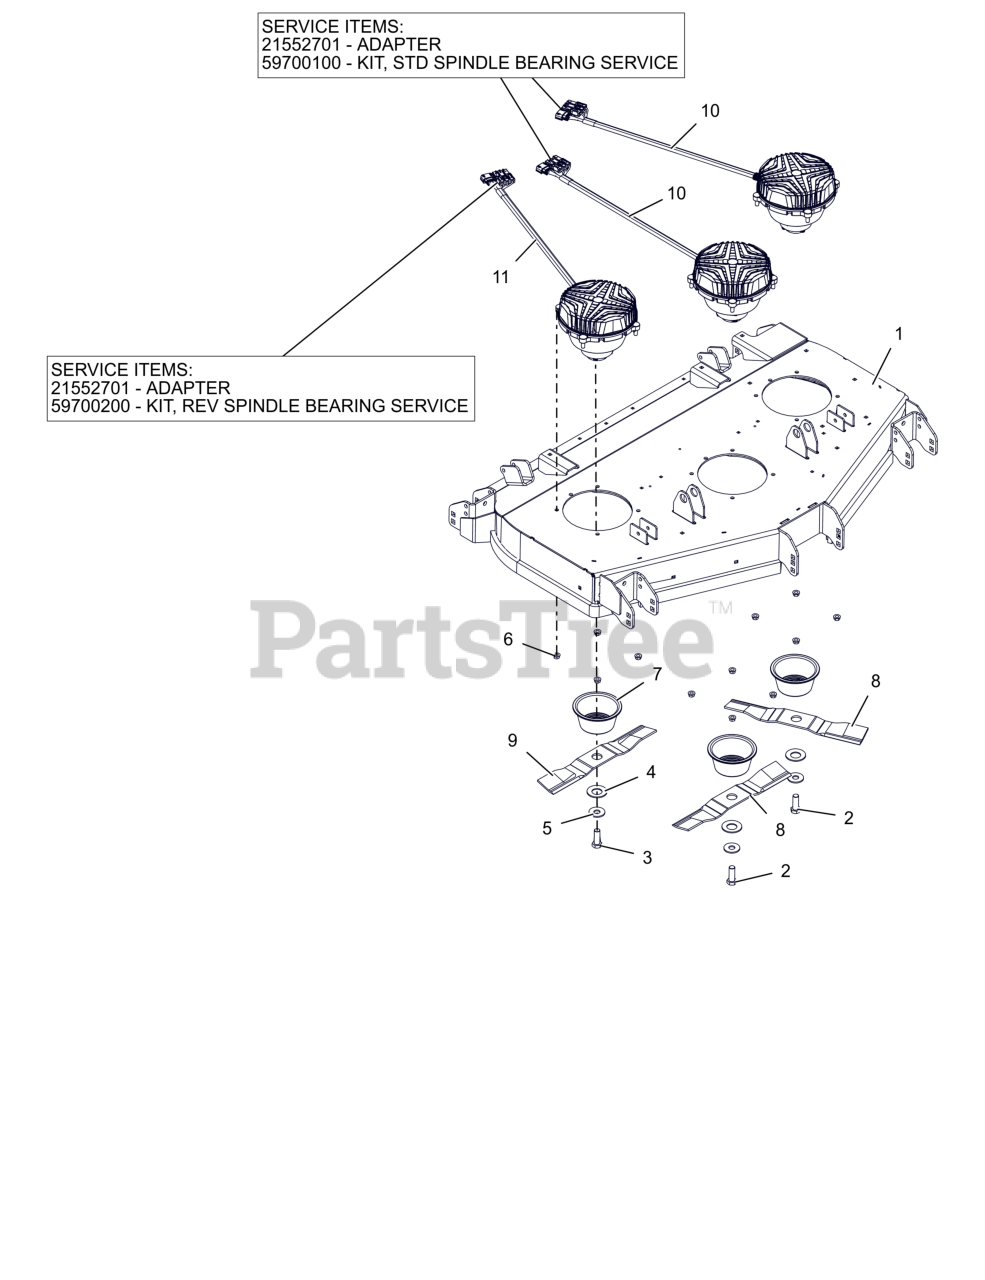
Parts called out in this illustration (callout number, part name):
1	WLDMT-48" PSEV REAR DISCH DECK
2	BLT, HEX .62-18X1.75 G8 ZCC
3	BLT, HEX 0.625-11X1.75 GR8 ZCC LH
4	WSHR, BLVL - .56X28.5X3 PHOS.COAT
5	WSHR, HRDN 0.687X1.75X0.134 HRD
6	NUT-LK-CTR-FLG .375-16 GF ZCC
7	GUARD, SPINDLE LOWER
8	BLADE, MOWER -16.190" EFF CW
9	BLADE, MOWER -16.190" EFF CCW
10	MOTOR, DECK - 48"/52" CW
10	ADAPTER
10	KIT, STD SPINDLE BEARING SERVICE
11	MOTOR, DECK - 48"/52" CCW
11	ADAPTER
11	KIT,REV SPINDLE BEARING SERVICE
